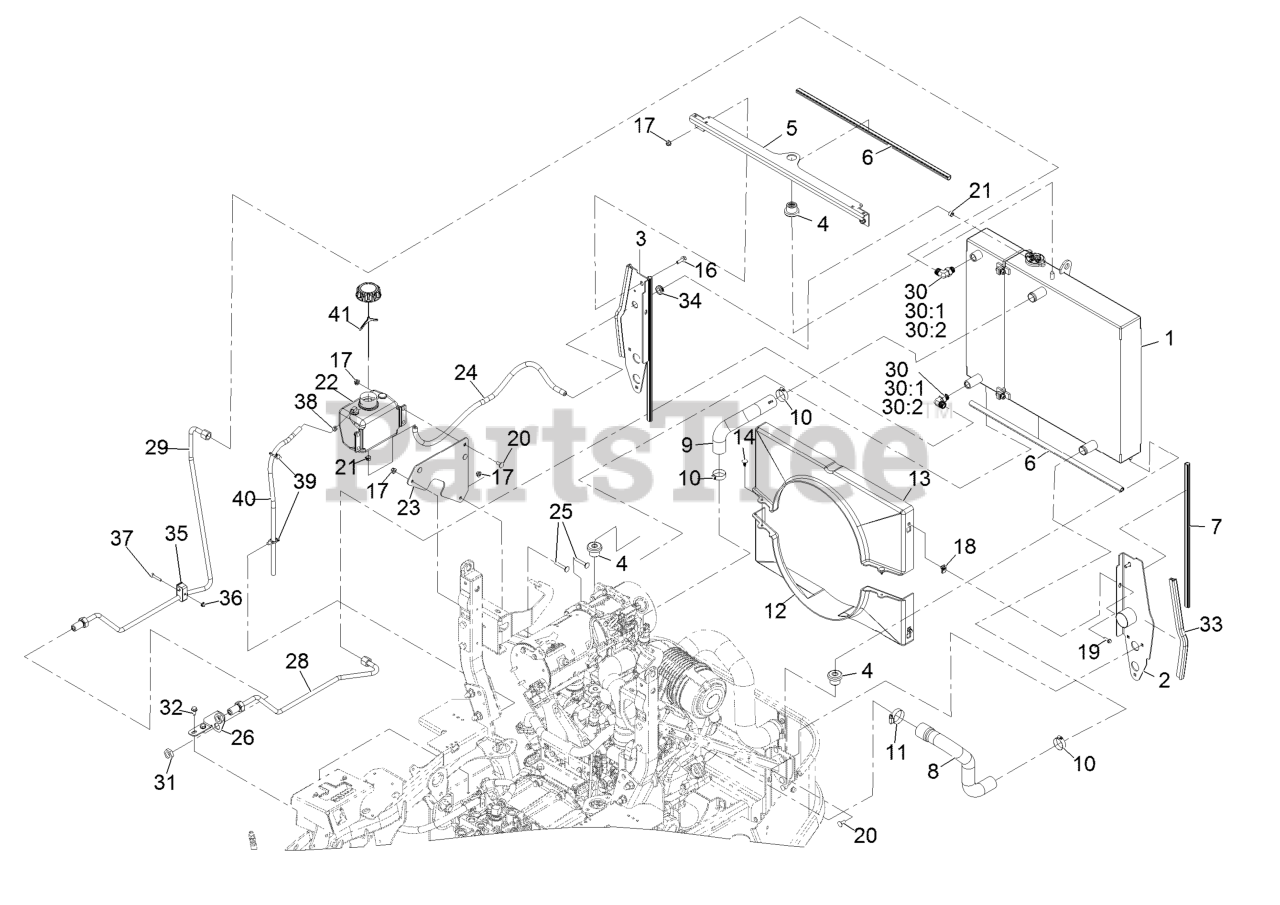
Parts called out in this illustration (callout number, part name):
1	Cooling ASM
2	Support-Radiator, LH
3	Support-Radiator, RH
4	Mount-Isolator
5	Bracket-Cooling, Top
6	Seal-Bulb
7	Seal-Bulb
8	Hose-Radiator, Lower
9	Hose-Radiator, Upper
10	Clamp-Hose
11	Clamp-Hose
12	Shroud-Bottom
13	Shroud-Top
14	Plug-Plastic
16	Screw-HH Flg 5/16-18 X 1
17	Nut-Nyloc 5/16-18 Flg
18	Nut-Retainer-Panel 1/4-20
19	Screw-Machine 1/4-20 X 3/4
20	Bolt-Carriage 5/16-18 X 3/4 Short Neck
21	Clamp-Hose
22	Tank-Overflow, W/Cap
23	Bracket-Bottle
25	Bolt-Carriage 3/16-18 X 2
26	Bracket-Bulkhead
28	Hydraulic Tube ASM
29	Hydraulic Tube ASM
30	Fitting-Elbow, 90 DEG
30:1	O-Ring
30:2	O-Ring
31	Nut-Bulkhead
32	Screw-HWH 5/16-18 X 3/4 Tf
33	Seal-Bulb
34	Grommet
35	Clamp-Twin
36	Nut-Nyloc 1/4-20 Flg
37	Screw-HH 1/4-20 X 1 3/8
38	Clamp-Hose
39	Clip-Tie
40	Hose-Fuel
41	Cap-W/Tether, 2.25
